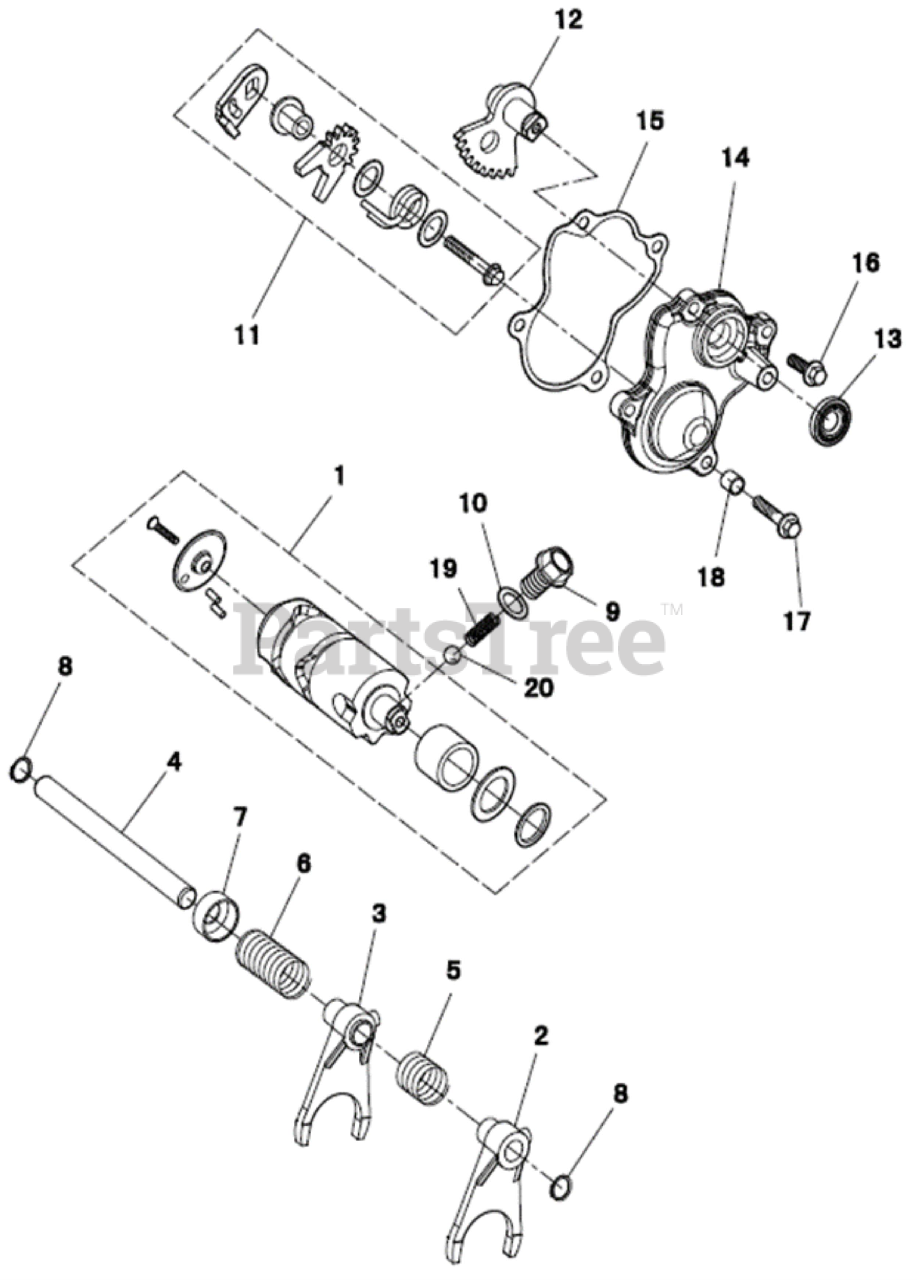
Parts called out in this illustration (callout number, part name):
1	Drum,Shift
2	Shifting Fork
3	Shifting Fork
4	Shift Rail
5	Spring, R gear
6	Spring,HL gear
7	Spring seat,Shift Rail
8	Circlip for shaft 12
9	Hollow Bolts M14X1.5X21
10	Copper Washer 14X21X1
11	Shift Dialing Plate Assy
12	Shiftshaft Assy
13	Oil Seal 15X25X5
14	Shiftshaft Cover
15	Gasket,Shiftshaft Cover
16	Hexagon flange bolts M6X20
17	Hexagon flange bolts M6X30
18	Pin,Dowel 8X12
19	Spring 24X1
20	Steel Ball 9.5
